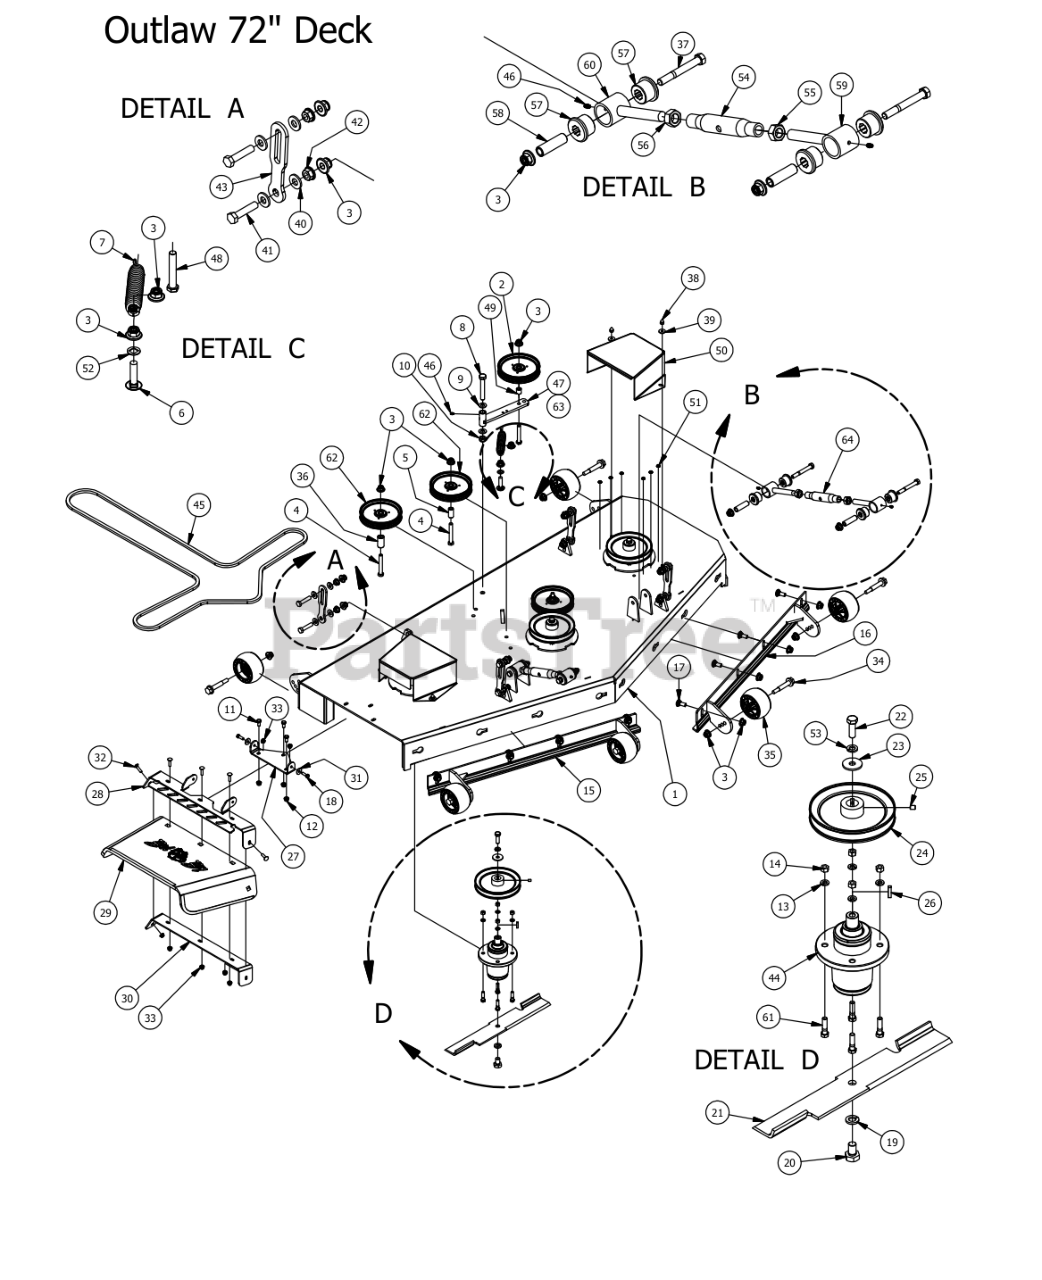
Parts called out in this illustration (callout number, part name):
1	2015 72" Deck
2	5-3/4 Idler Pulley-Don Dye
3	1/2-13 Nylon Flange Nut
4	1/2 x 3 1/2 Flange Bolt Grade 8
5	.502 ID X.750 OD X 1.500 Long Spacer
6	1/2 x 2" Carriage Bolt
7	2015 Deck Idler Spring Outlaws
8	5/8" x 4" Hex Bolt
9	.630 ID Plastic Washer
10	5/8-11 Nylon Insert Jam Half Nut
11	3/8" x 3/4" Hex Bolt
12	3/8" Flange Nut
13	3/8 Lockwasher Zinc
14	3/8-16 Hex Nuts Zinc
15	72" Deck Adustable Front (Right)
16	72" Deck Adjustable Front (Left)
17	1/2" x 1 1/4 Carriage Bolt
18	5/16" x 1" Bolt
19	5/8" Lock Washer
20	5/8" x 1 1/2" Grade 8 Hex Bolt (Fine)
21	72" High Lift Fusion Blade
22	1/2"-20 x 1 1/2 - Grade 5 Fine Thread Bolt
23	1/2 Belleville Washer
24	7" Deck Pulley
25	5/16 Set Screw
26	1/4" x 1" Key
27	Discharge Chute Hanger (deck mounted)
28	60" Discharge Chute Upper Hanger
29	Rubber Discharge Chute
30	60" Discharge Lower Bracket
31	.360 ID Plastic Washer
32	5/16" x 1 1/4" Carriage Bolt
33	5/16" Nylock Flange Nut Zinc
34	Deck Wheel Bolt
35	Anti-Scalp Rollers
36	1 3/4" Pulley Spacer
37	1/2" x 4" Bolt (Grade 8)
38	Acorn nut-pulley Cover
39	.360 ID Plastic Washer-Black
40	.505 Nylon Spacer
41	1/2-13X 2-1/4 GR Hex Bolts
42	1/2" Flange Nut
43	Deck_Hanging_Tab
44	OUTLAW SPINDLE ASSEMBLY
45	B202 Belt for 72" Outlaw
46	1/4" Press in Grease Fitting
47	Deck Idler
48	1/2-13 x GR 5 Hex Bolt Zinc
49	Spacer 3/4 OD x 1/2 ID x 3\4 Length
50	72 Spindle Cover
51	Black, Round Stick-On Rubber Bumpon
52	.517 Square Hole Round Washer
53	1/2" Lock Washer
54	2015 Outlaw Toplink Body
55	3/4-10 Left-Handed Hex Nuts Zinc
56	3/4-10 Hex Nuts Zinc
59	Turn Left-Handed
60	Right-Handed End
61	3/8" x 1 1/2" Hex Bolt
62	5-3/4 Idler Pulley-Capitol Stampings
63	Deck Idler Assembly - Includes parts: 2,3,47,48,49
64	Turnbuckle Assembly
